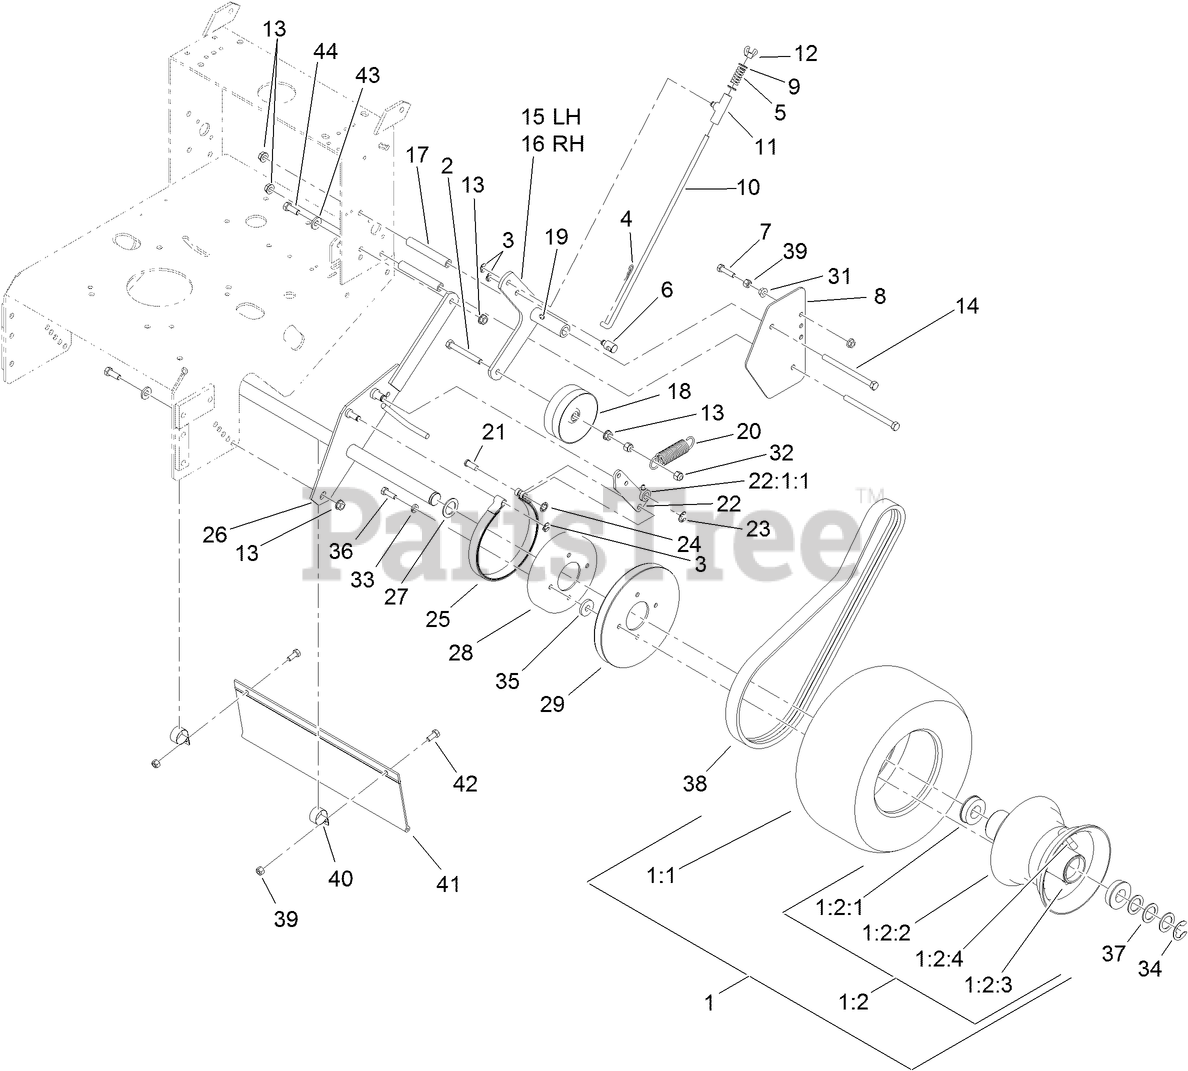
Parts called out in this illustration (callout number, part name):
1	WHEEL AND TIRE ASM
1:2	WHEEL AND HUB ASM
1:2:1	BEARING-FLANGED
1:2:2	HUB and BEARING ASM
1:2:3	HUB and BEARING ASM
1:2:4	HUB and BEARING ASM
2	SCREW-HH
3	RING-RETAINING
4	PIN-COTTER
5	SPRING-COMPRESSION
6	SWIVEL-LEVER, DRIVE
7	SCREW-HH, SPECIAL
8	SHIELD-WHEEL, DRIVE
9	WASHER-PLAIN
10	LINKAGE-BRAKE
11	SWIVEL-BRAKE
12	WINGNUT-NYLOCK
13	NUT-HHF, WHIZ
14	SCREW-HH
15	ARM-IDLER, LH
16	ARM-IDLER, RH
17	SPACER-SHIELD
18	IDLER-WHEEL, DRIVE
19	FITTING-GREASE
20	SPRING-EXTENSION
21	PIN-CLEVIS
22	ARM-BRAKE
22:1:1	BUSHING-ZERK
23	RING-RETAINING, EXTERNAL
24	RING-RETAIN,PUSH,EXT,FLAT
25	BAND-BRAKE
27	WASHER-SPACER
28	DRUM-BRAKE
29	SHEAVE-WHEEL, DRIVE
31	NUT-HF
32	NUT-LOCK, NI
33	WASHER-LOCK
34	RING-SNAP
35	WASHER
36	SCREW-HH
37	WASHER-SPACER
38	BELT-DRIVE, WHEEL
39	NUT-LOCK, NI
40	CLAMP-R
41	SHIELD-TRAILING
42	SCREW-HH
43	WASHER-BELLEVILLE
44	SCREW-HH
